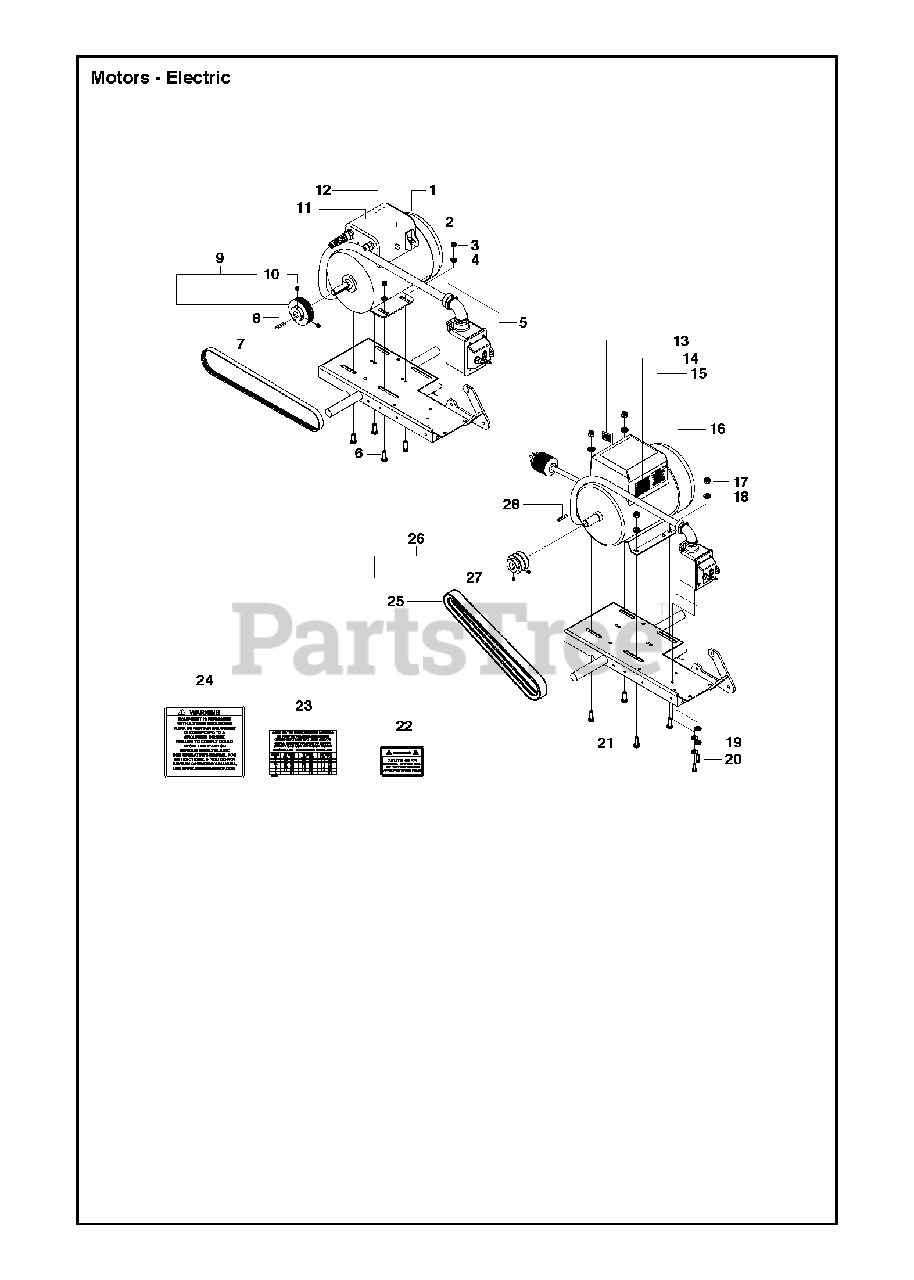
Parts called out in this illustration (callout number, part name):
3	NUT
16	MOTOR1.5 HP-60 Hz-1 Ph
16	MOTOR2.0 HP-50 Hz-1 Ph
16	MOTOR3.0 HP-60 Hz-1 Ph
16	TBD3.0 HP-60 Hz-3 Ph
17	NUT
18	WASHER
